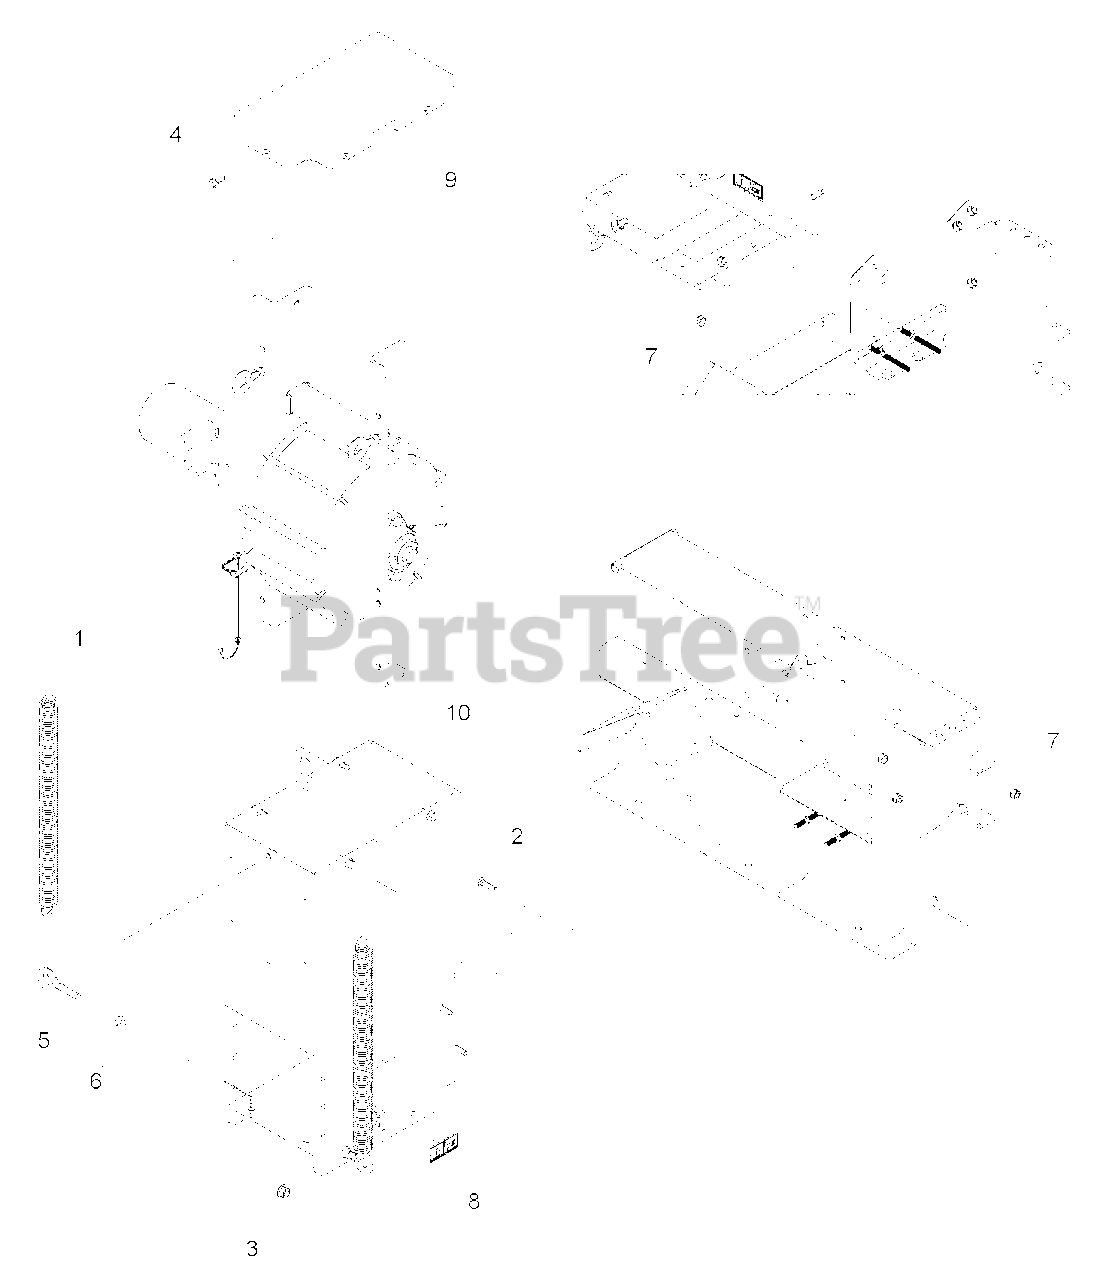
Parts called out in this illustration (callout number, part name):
1	SPRING, EXTENSION
2	BOLT, 3/8-16 X 1-1/2 GR5 CRG
3	NUT, 1/2-13 NYLOCK FLANGE
4	BOLT, 3/8 X 1 FLANGE NC
5	EYEBOLT, 1/2-13 X 2
6	NUT, 1/2 SPIRAL LOCK NC ZP
7	NUT, 3/8-16 NYLOCK FLANGE
8	DECAL, CRUSHING ISO
9	WELDMENT, TOP ROLLER COVER
10	WELDMENT, ROLLER SUPPORT
